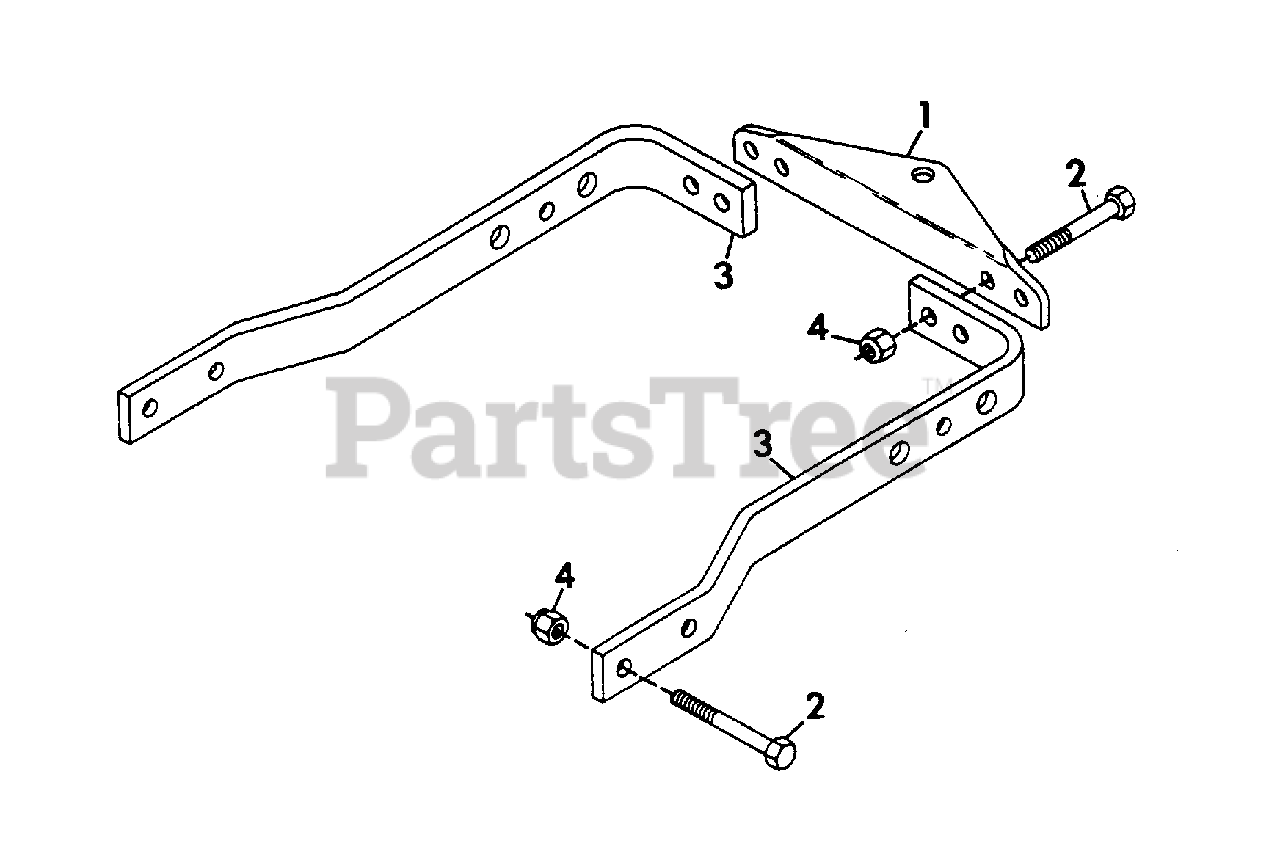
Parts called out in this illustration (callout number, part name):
1	PLATE, HITCH
2	BOLT, HEX 1/2-13X1.75
3	ARM, REAR HITCH
4	NUT, LOCK 1/2-13
